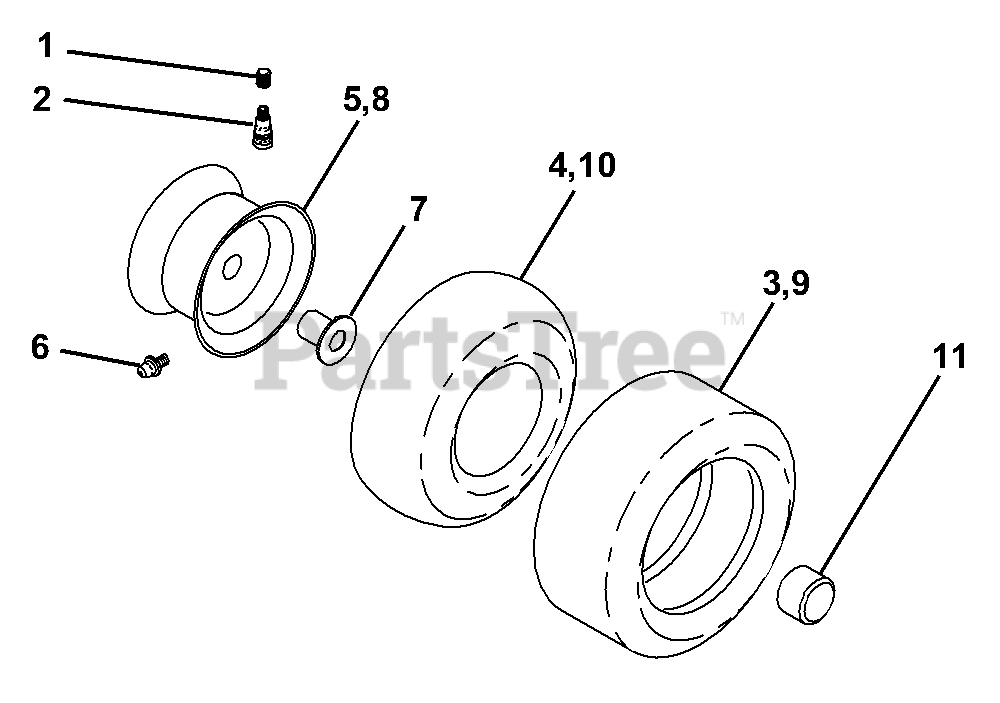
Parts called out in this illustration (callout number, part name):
1	Cap Valve Tire
2	Stem Valve
3	Tire F Ts 15 X 6 0 - 6 Service
4	Tube Front (Service Item Only)
5	Rim Asm 6"front Silver Service
6	Fitting Grease (Front Wheel Only)
7	Bearing Flange (Front Wheel Only)
8	Rim Asm 8"rear Silver Service
9	Tire R Ts 20 x 10-8 C Service
10	Tube Rear (Service Item Only)
11	Cap Axle Blk 1 50 X 1 00
